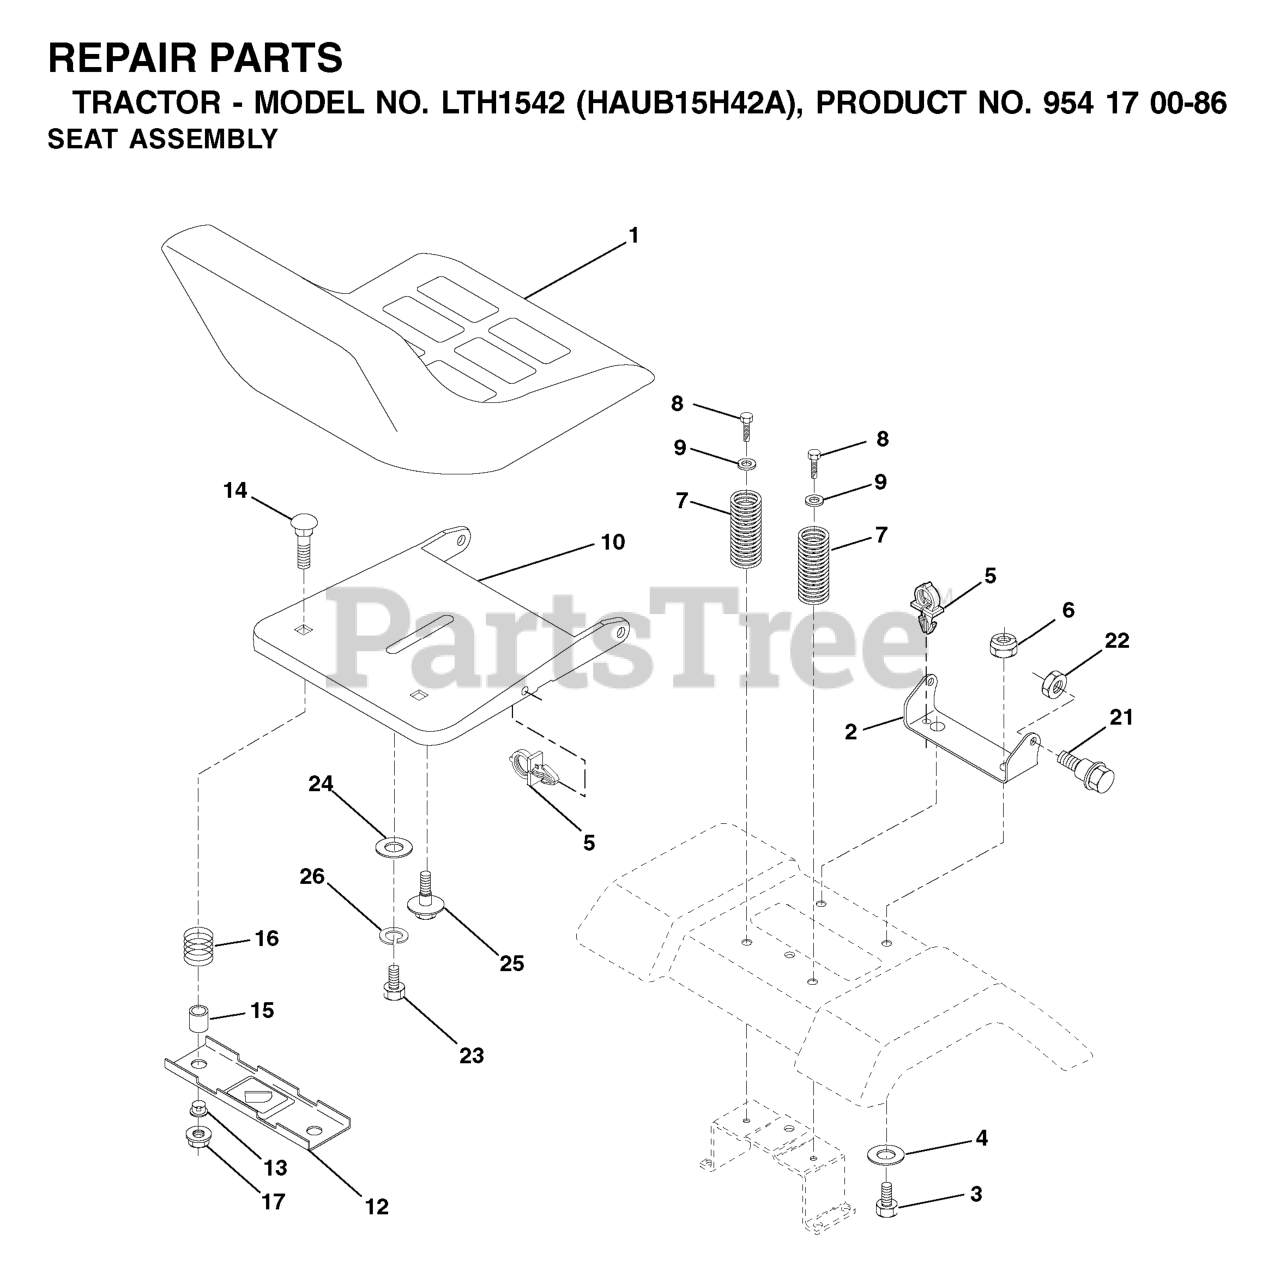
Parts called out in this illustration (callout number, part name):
1	CHASSIS W/DECALS
2	SWITCH, INTERLOCK
3	RETAINING RING, 7/8"
4	TAPPED PLATE
5	RUBBER GROMMET
6	FUEL CAP ANTI-SPLASH
7	BOLT 5/16-18 X 3/4
8	WASHER - 3/16 LOCK ZD
9	CONSOLE
10	FENDER LEFT
12	FOOT REST GRAY
14	BOLT, SHOULDER
15	SLIP, MATTING
16	STEM, FUEL TANK
17	SCR #10-12X3/4 HEX WAS HD ZD
19	SEAT MOUNT, BLACK
20	SEAT.XH150.LOWBACK.GREY.ZTR
21	BSHG .875 X 1.375 X .074 ZD
22	SCREW #10-24 X 5/8
23	SCREW 1/4 X 5/8
25	NUT 5/16 NYLOC
26	KNOB W/STUD
27	REAR BRKT, TOOL BOX, PAINTED
